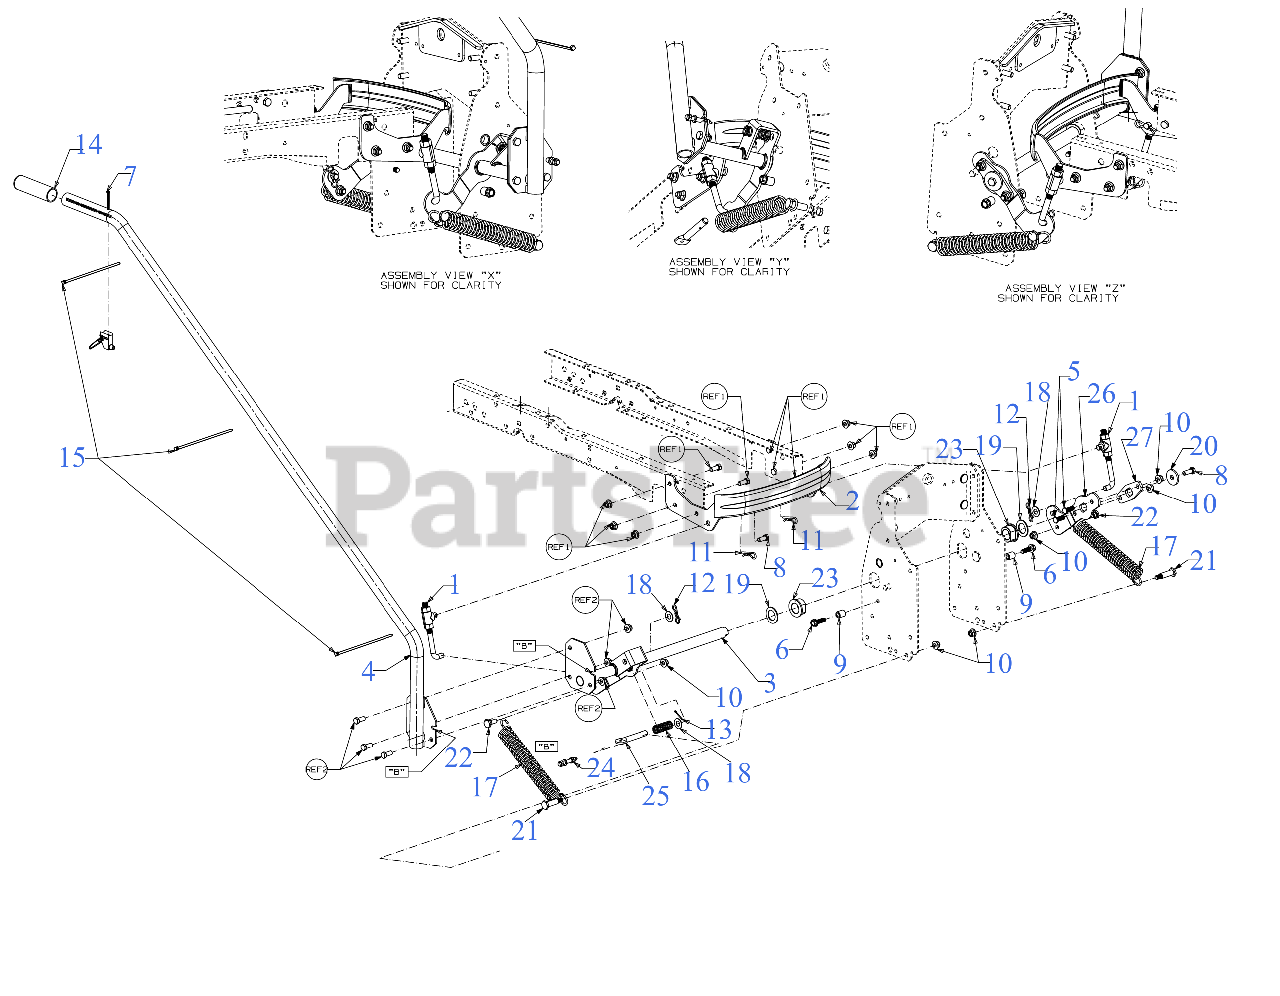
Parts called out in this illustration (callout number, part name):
1	LIFT ADJUSTMENT LINK
2	BUMPER ASSEMBLY (POWDER BLACK)
3	LIFT SHAFT ASSEMBLY
4	LIFT HANDLE ASSEMBLY (POWDER BLACK)
5	SCREW 3/8-16X1.0 GR5 SPEC
6	SCREW 3/8-16 X1.250
7	SCREW #10-24 x 1.75
8	SCREW 3/8-16X1.0 GR5
9	SPACER .385 x .623 x .750
11	HITCH PIN CLIP
12	BOW TIE COTTER PIN
13	COTTER PIN 3/32 x 1.25
14	GRIP 1.188 x 4.562
15	7" CABLE TIE
16	COMPRESSION SPRING .772 OD x 1.95
17	EXTENSION SPRING 1.45 OD x 6.00
18	FLAT WASHER .510X.995
19	FLAT WASHER 1.031 X1.62 X.095
20	FLAT WASHER .45 x 1.5 x .172 HT
21	SHOULDER SCREW .498 DIA x 1.450-THD
22	SHOULDER SCREW
23	FLANGE BEARING
24	LIFT CABLE
25	LIFT LOCK ROD
26	LIFT BRACKET
27	LIFT LINK ADAPTER PLATE
